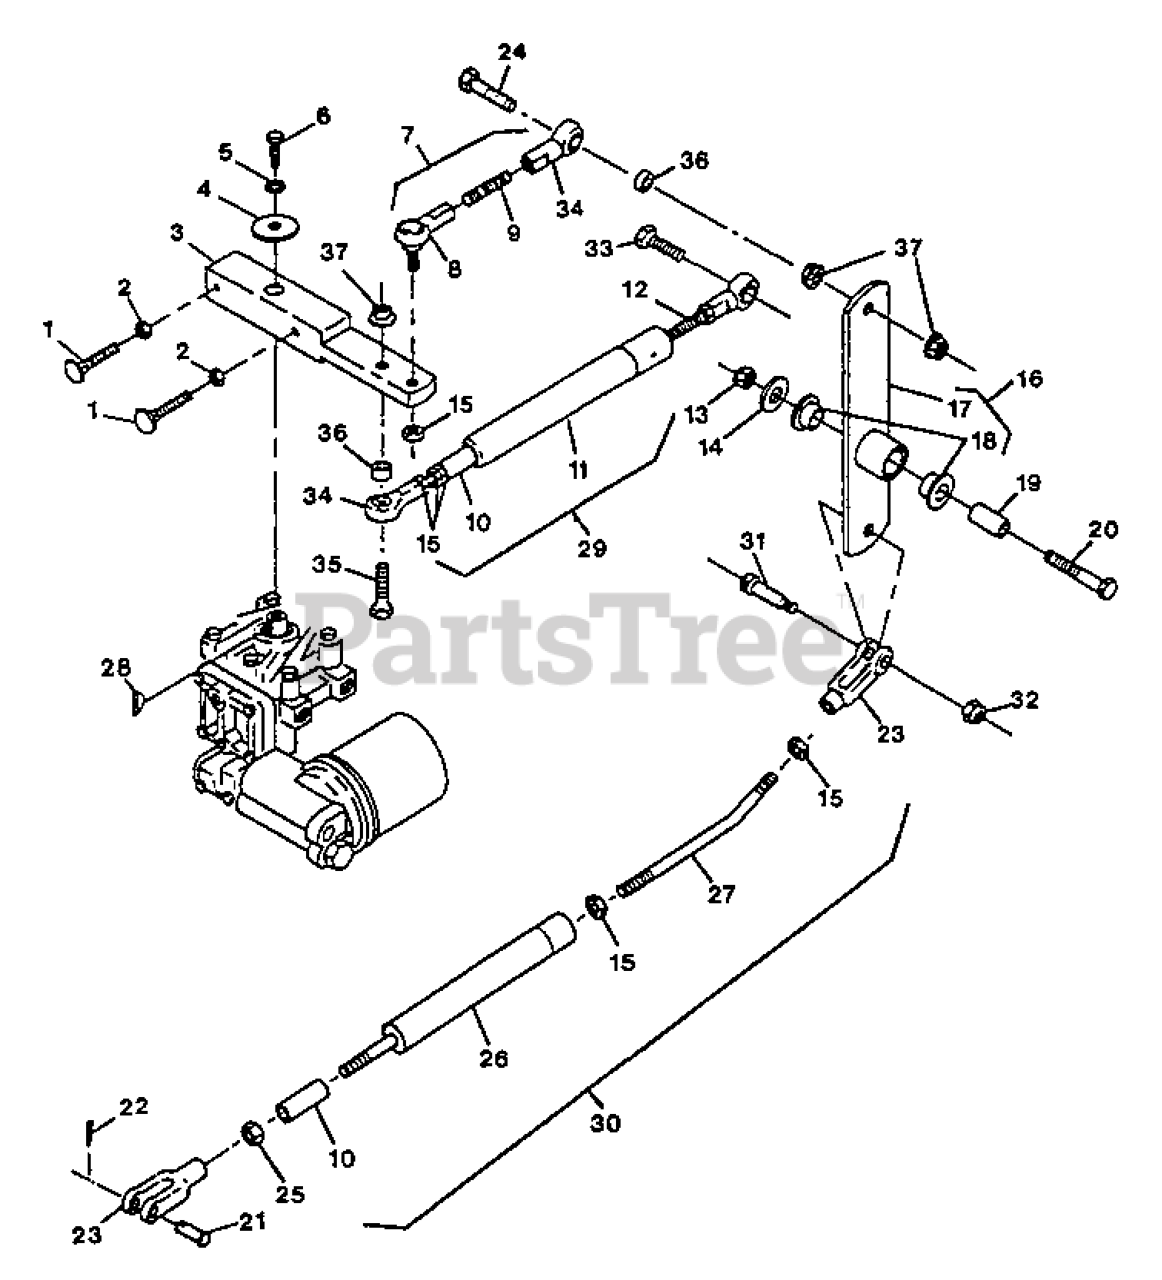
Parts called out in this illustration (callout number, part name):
2	NUT-HEX
3	WLD,ARM TRANSAXLT
4	WASHER-RETAINER, PULLEY
5	WASHER-LOCK
6	Capscrew, 1/4-20 X 1-1/2
8	BALLJOINT
9	ROD END PLTD.
10	BUSHING,SPRING GUIDE
12	ROD,END
13	NUT-LOCK, NI
14	WASHER-FLAT
15	NUT-JAM
17	WLD,IDLER LINKAGE
18	BEARING-CONTROL
19	BUSHING,MOTION LEVER
20	SCREW-HH
21	PIN-CLEVIS
22	PIN-COTTER
23	YOKE-ADJUSTABLE
24	SCREW-HH
25	NUT-HEX
27	LINKAGE,ROD
28	KEY-WOODRUFF
30	ASM,PEDAL OVERRIDE
31	SCREW-HSH
32	NUT-LOCK, NI
33	SCREW-HH
34	BALLJOINT-RH
35	SCREW-HH
36	SPACER-PLATED
